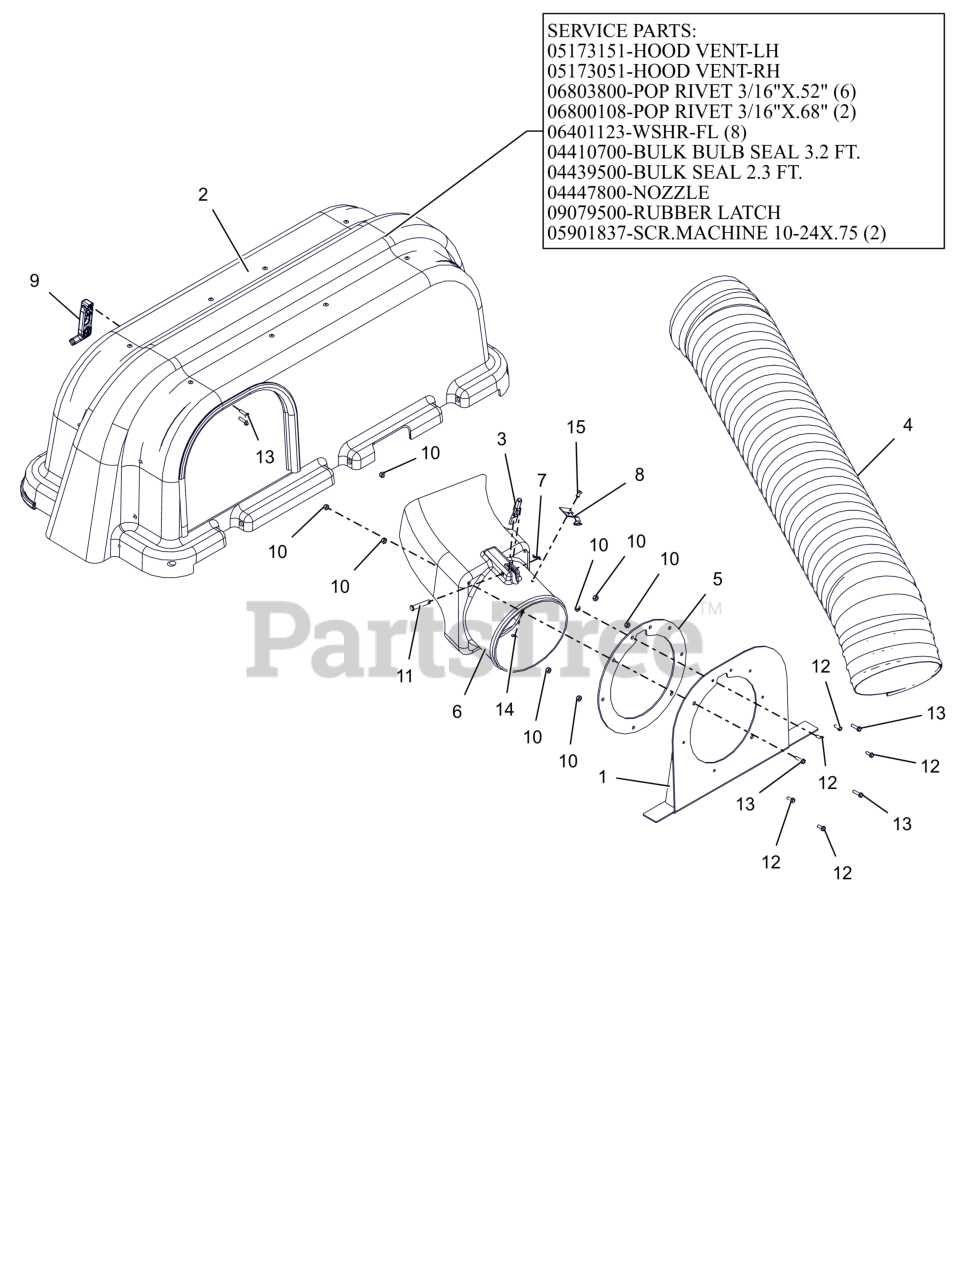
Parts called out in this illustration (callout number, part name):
1	WLDMT, TUBE SUPPORT
2	KIT, HOOD ASSEMBLY
2	VENT, BAGGER LH HOOD
2	VENT, BAGGER RH HOOD
2	RVT-POP.187X.527 DOME ST
2	.187X.6835 DOME ST
2	WSHR, FLT .219X.500X.049 ZCC
2	SEAL, BULB - BAGGER HOOD
2	SEAL, BULK
2	NOZZLE
2	LATCH, RUBBER
2	BLT, HWH #10-24X.75 ZCC
3	INDICATOR, FLOW
4	HOSE, FLEXIBLE-56"
5	SEAL, UPPER BOOT
6	BOOT, UPPER
7	PIN, HAIR #225 .072X1.09
8	THUMB LATCH
9	LATCH, RUBBER
10	NUT-LK-NYL #10-24 G2 ZCC
11	PIN-CLEV .309 X 1.625 YWZC
12	BLT, HWH #10-24X.50 ZCC
13	BLT, HWH #10-24X.75 ZCC
14	WSHR, FLT .219X.500X.049 ZCC
15	RVT-POP.187X.527 DOME ST
